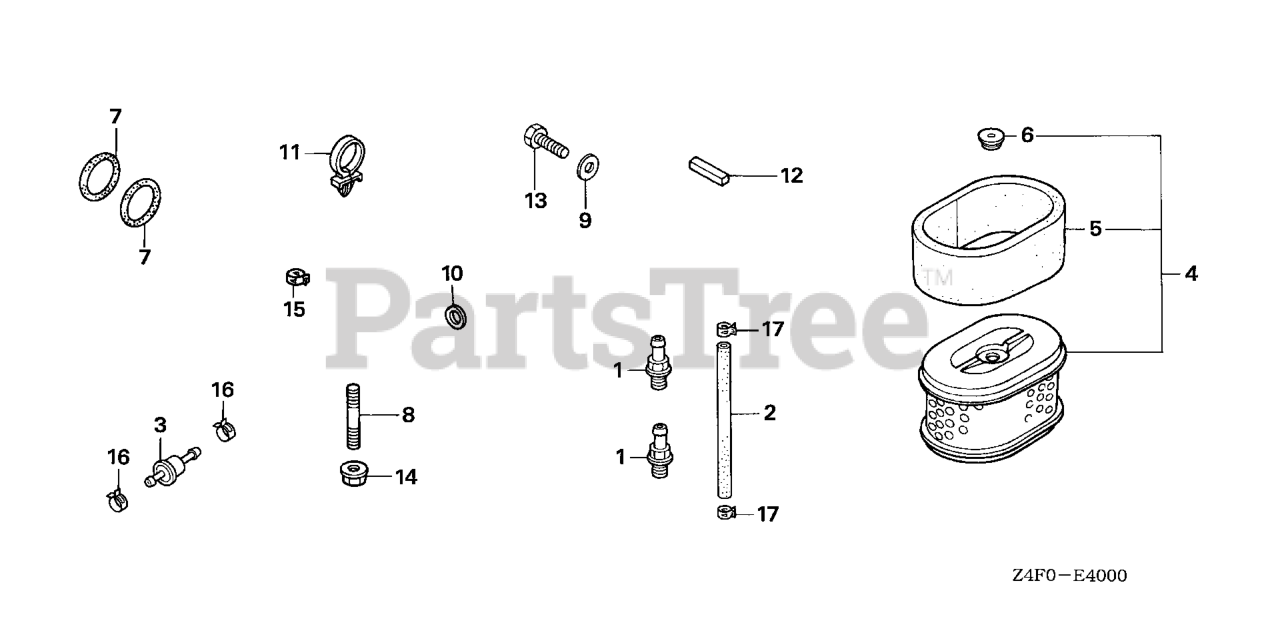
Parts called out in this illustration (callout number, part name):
1	JOINT, DRAIN
2	TUBE, DRAIN
10	WASHER, DRAIN PLUG (10.2MM)
17	CLAMP, TUBE (D12)
